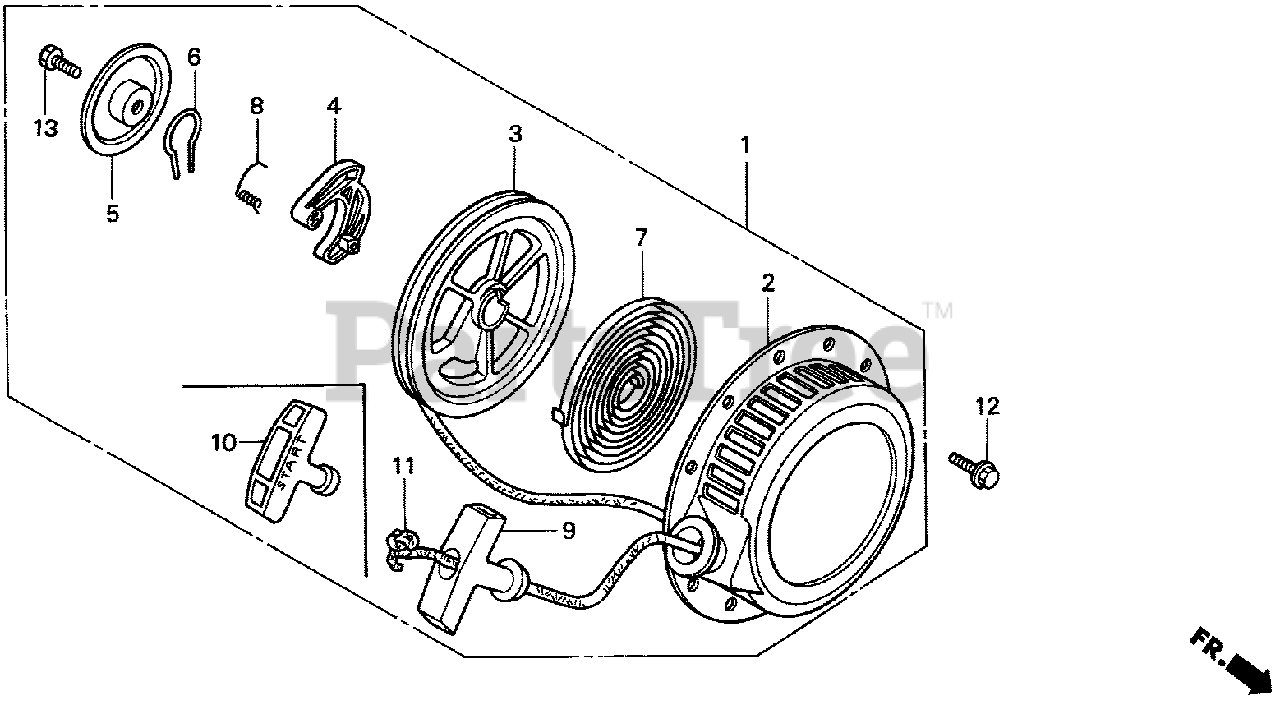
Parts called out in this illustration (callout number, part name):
1	STARTER ASSY., RECOIL *R8* (BRIGHT RED)
2	CASE, RECOIL STARTER *R8* (BRIGHT RED)
3	REEL, RECOIL STARTER
4	RATCHET, STARTER
5	PLATE, FRICTION
6	SPRING, FRICTION
7	SPRING, RECOIL STARTER
8	SPRING, RETURN
10	KNOB, RECOIL STARTER
11	ROPE, RECOIL STARTER
12	BOLT, FLANGE (6X10)
13	BOLT, HEX. (6X20)
